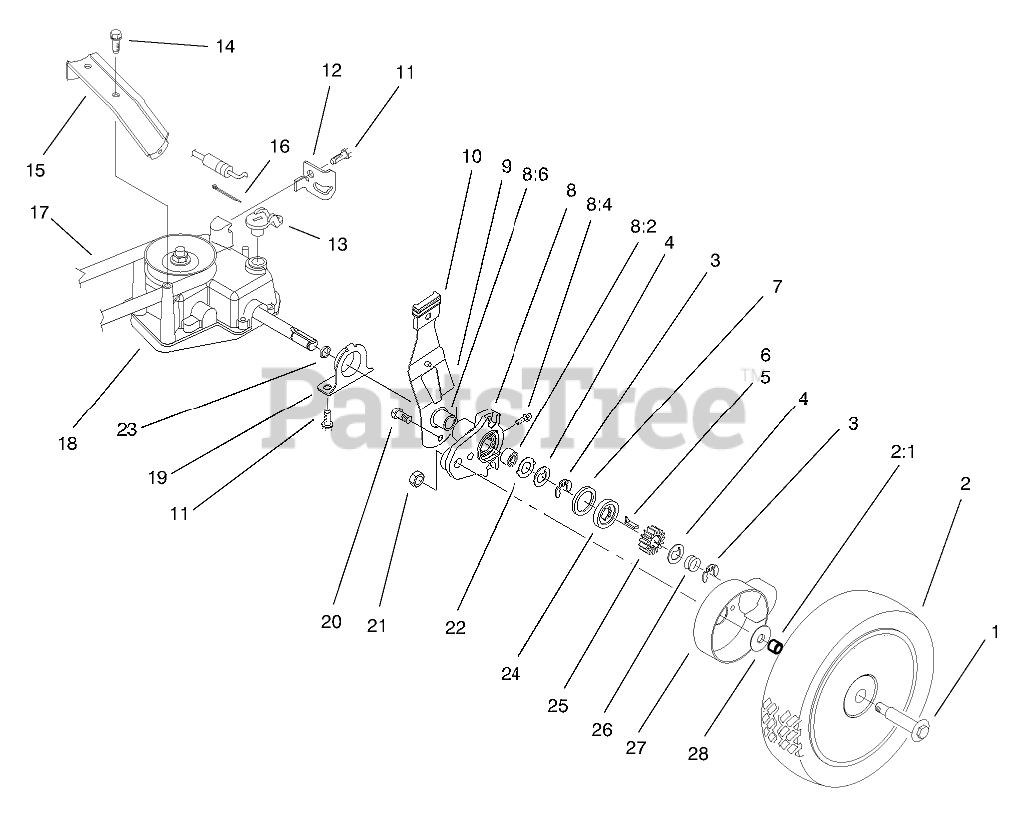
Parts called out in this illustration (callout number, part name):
1	WHEEL BOLT
2	WHL & TIRE ASSEMBLY
2:1	BUSHING
3	RING-CLIP, LOCKING
4	WASHER-THRUST, KEYED
5	KEY-ROCKING, LH
6	KEY-ROCKING, RH
7	RING-FRICTION
8	PIVOT ARM ASM
8:2	BEARING-ROLLER
8:4	FITTING-GREASE
8:6	BUSHING
9	SPRING ARM ASM
10	KNOB-ARM
11	SCREW-HWHTF
12	RETAINER-CABLE
13	LEVER-SHIFT
14	SCREW-HWHTF
15	Bracket-BeltGuide
16	PIN-COTTER
17	V-BELT
18	GEARCASE ASM
19	CAP-END
20	SCREW-HSH, THREAD FORMING
21	NUT-LOCK
22	WASHER-ARM, PIVOT
23	O-RING
24	WASHER-CLUTCH
25	GEAR-PINION
26	SPRING-COMPRESSION
27	COVER-WHEEL
28	SPACER-COVER, WHEEL
